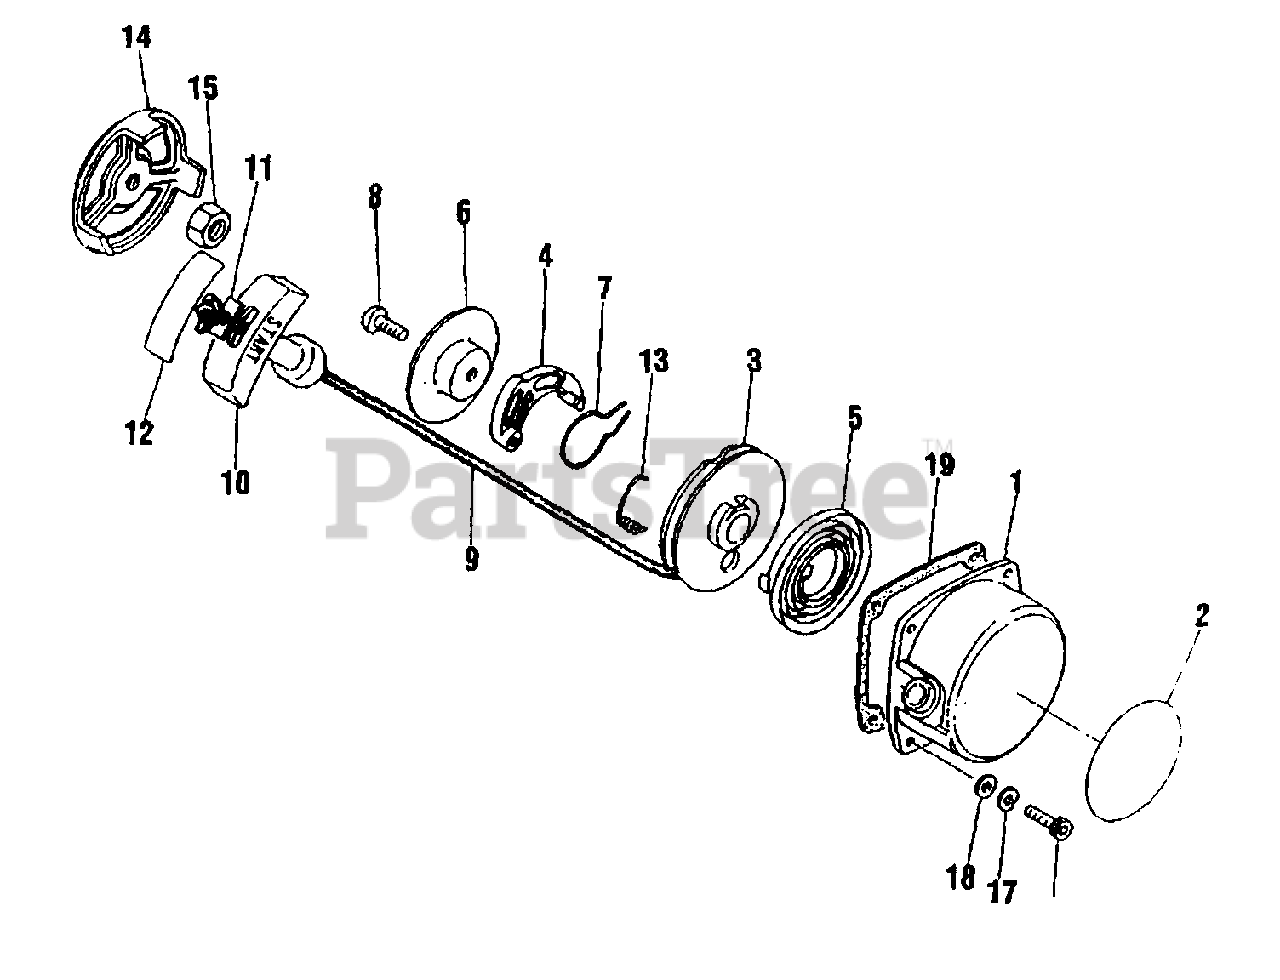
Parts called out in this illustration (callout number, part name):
1	CASE, STARTER
3	REEL, ROPE
4	PAWL, STARTER
5	SPRING, REWIND
6	PLATE, STARTER
7	SPRING
8	SCREW
9	ROPE
10	GRIP, STARTER
11	RETAINER, ROPE
12	TAPE
13	SPRING, RETURN
14	CATCHER, STARTER
15	NUT - 8
17	LOCKWASHER - 4
18	WASHER - 4
19	GASKET
